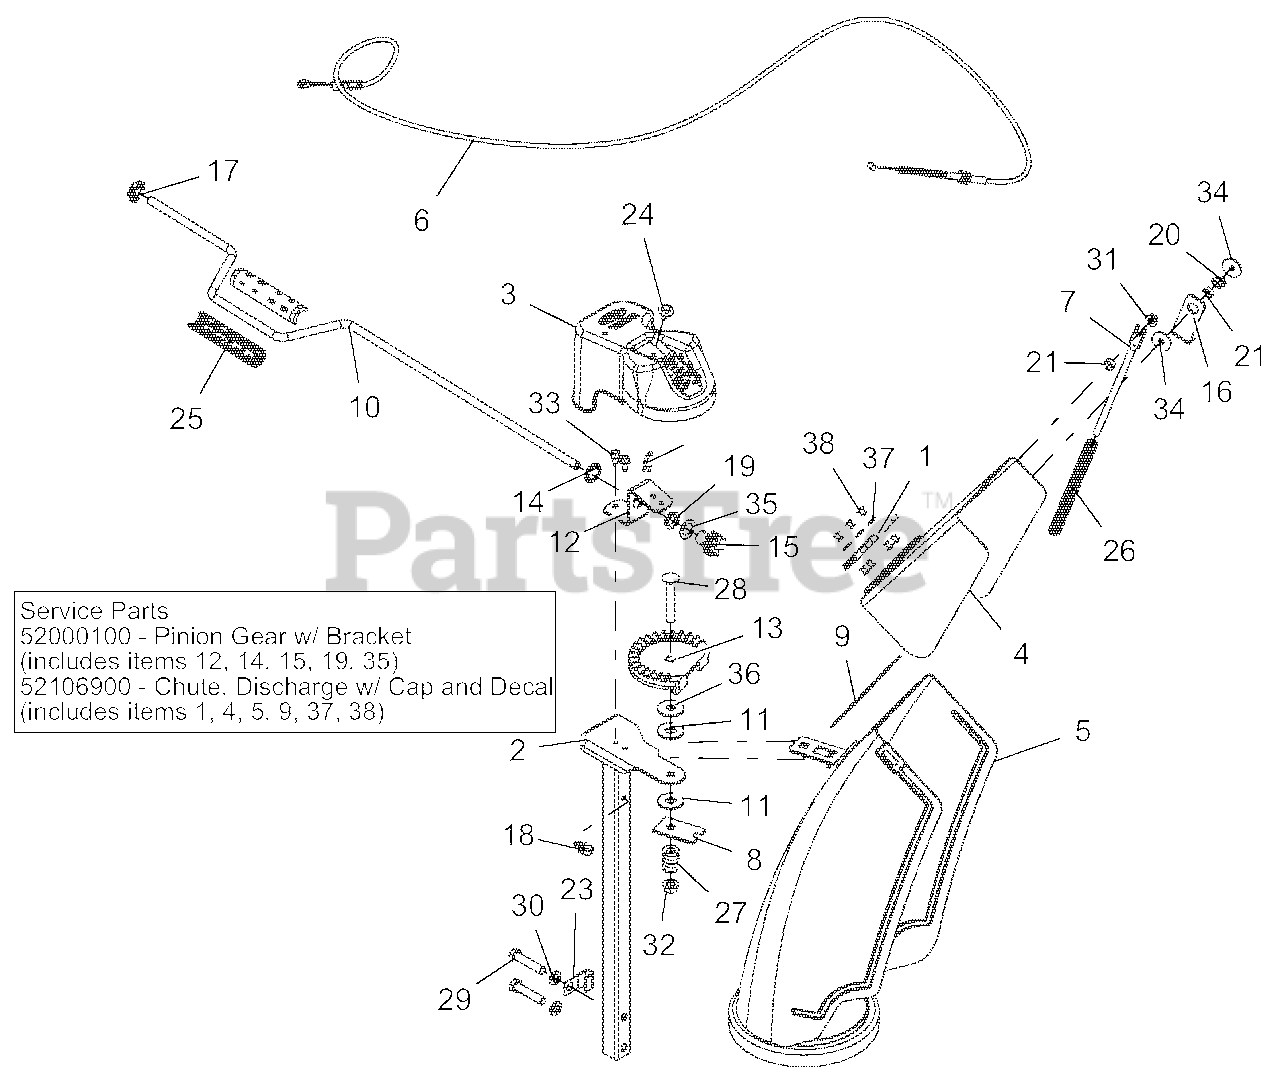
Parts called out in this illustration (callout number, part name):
2	PEDESTAL, CHUTE - CRANK
3	GEAR COVER ASSY LG SHEAR BOLT
4	CAP,LARGE,REMOTE
5	CHUTE,DISCHARGE,RMT,ID
6	CABLE, DEFLECTOR - DELUXE
7	ROD, DEFLECTOR CAP
8	PLATE, FRICTION
9	CAP SEAL 5.50
10	ROD, CHUTE CRANK
11	FRICTION WASHER
12	BRACKET, PINION GEAR
13	CHUTE GEAR
14	PUSHNUT .625
15	PINION GEAR - CHUTE
16	BRACKET, CABLE ANCHOR
17	CRANK BUSHING, NYLON CHUTE BK
18	CLIP, CABLE GUIDE
19	BUSHING, POLYLINER-.63 SNAPIN
20	BUSHING, POLYLINER-.50 SNAPIN
21	BSHG-SLV .265X.500X.219
22	PIN, SPRING CLIP
23	J-CLAMP
24	SCR-TAP .25-20X.50 LGHWH TR YZ
25	KNOB, CRANK-SNAP
26	SG-COMP .08X.40X6.50 14#/IN
27	SG-COMP .187X.56X1.62
28	@BLT-RDHDSQNK .38-16X2.50 G5YZ
29	@BLT-HEX .38-16X1.75 GR5 YWZC
30	@WSHR-LK .38X.094 REG YWZC
31	@NUT-LK-CTR-FLG .25-20 YWZC
32	@NUT-LK-TOP-FLG .38-16 YWZC
33	SCR-TAP .25-20X.50 HWH TR YWZ
34	WSHR-FL-STL .281X1.000X.063
35	WSHR-THRST .625 X 1.0 X .03
36	@WSHR-FL-STL .406X1.25X.10 ZC
37	WSHR-FL-STL .196X.500X.06 YZ
38	RVT-POP .187 YZ
39	PINION GEAR W/BRACKET
40	KIT, DISCHARGE CHUTE W/DEF ID
